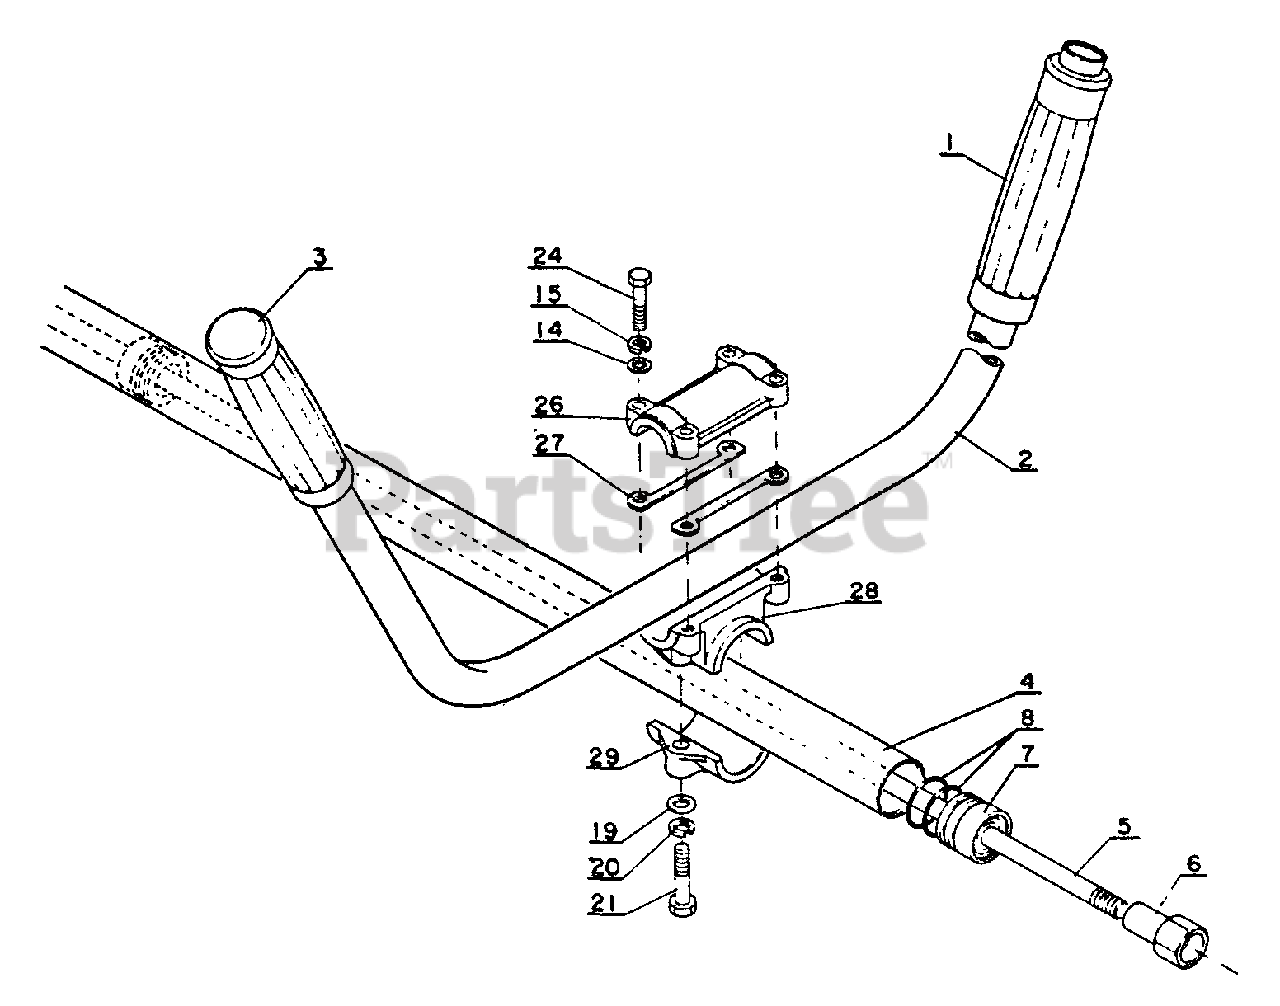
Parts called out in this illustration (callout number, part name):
1	U-HANDLE
2	GRIP, HANDLE
3	GRIP, HANDLE - LEFT
4	PIPE, MAIN
5	DRIVESHAFT
6	DRIVESHAFT
7	STOPPER
8	O-RING - 22
14	WASHER - 5
15	LOCKWASHER - 5
19	WASHER - 6
20	LOCKWASHER - 6
21	BOLT - 6X32
24	BOLT - 5X25
26	HANDLE BRACKET KIT
28	HANDLE BRACKET KIT
29	HANDLE BRACKET KIT
